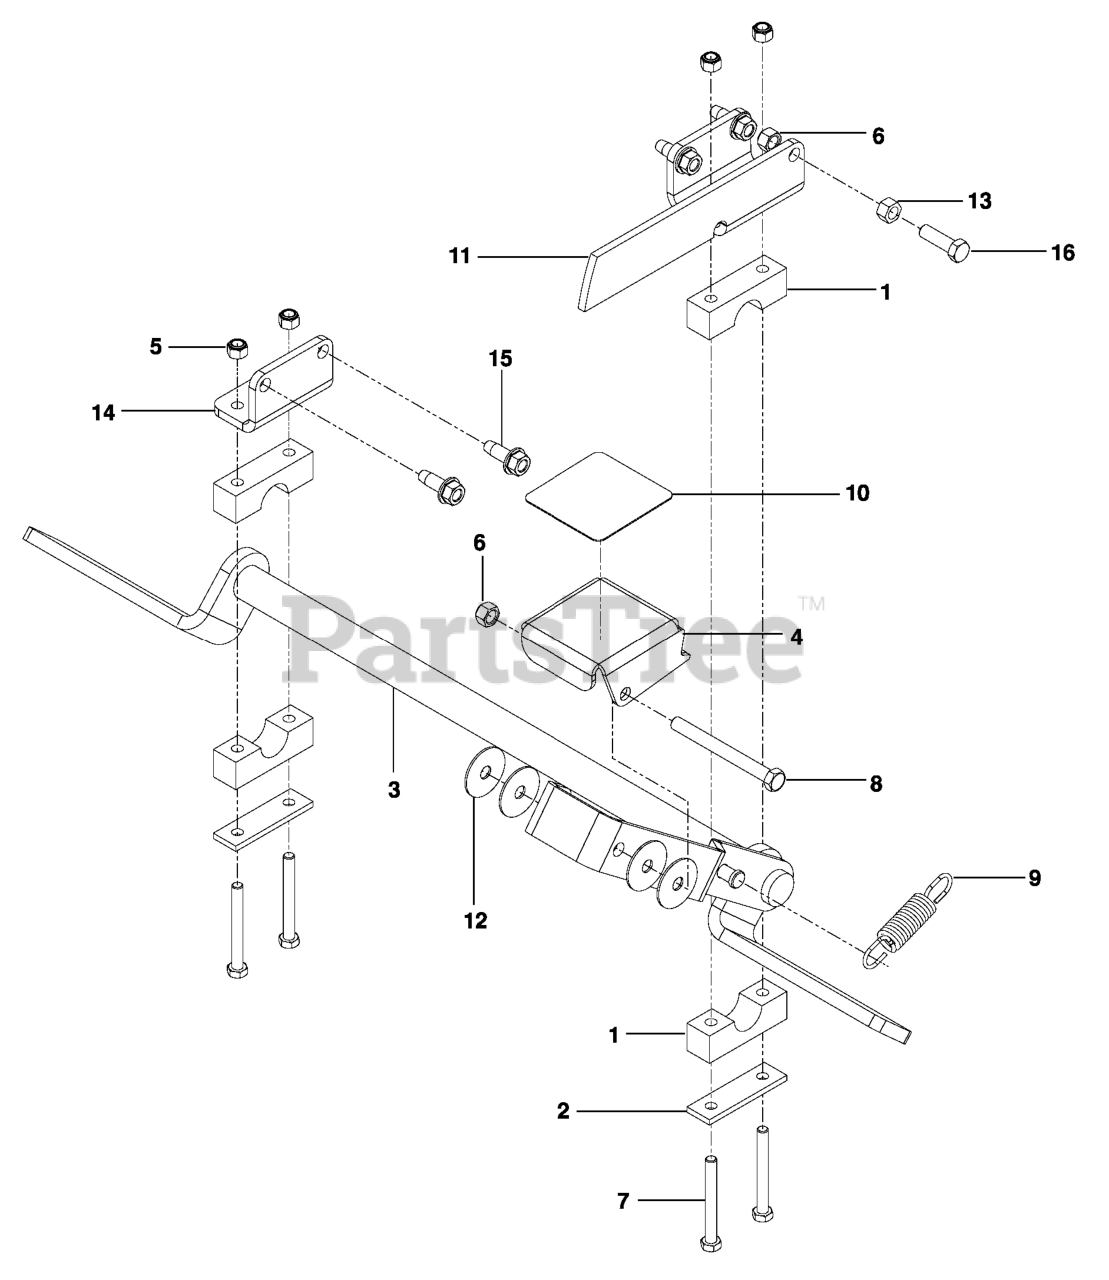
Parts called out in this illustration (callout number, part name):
1	PILLOW BLOCK
2	REINFORCEMENT BAR
3	PARK BRAKE
4	PEDAL, BLACK
5	NUT 5/16 NYLOC
6	NUT 3/8-16 NYLOC
7	HCS 5/16C X 2-3/4
8	HCS3/8-16.X
9	SPRING, EXTENSION
10	ANTI-SKID PAD
11	SUPPORT PLATE, P. BRAKE RH BLK
12	WASHER, FRICTION
13	NUT 3/8-16
14	SUPPORT PLATE, P. BRAKE LH BLK
15	BOLT 3/8-16 X 1.0
16	HCS 3/8C X 1 1/4 GR5
